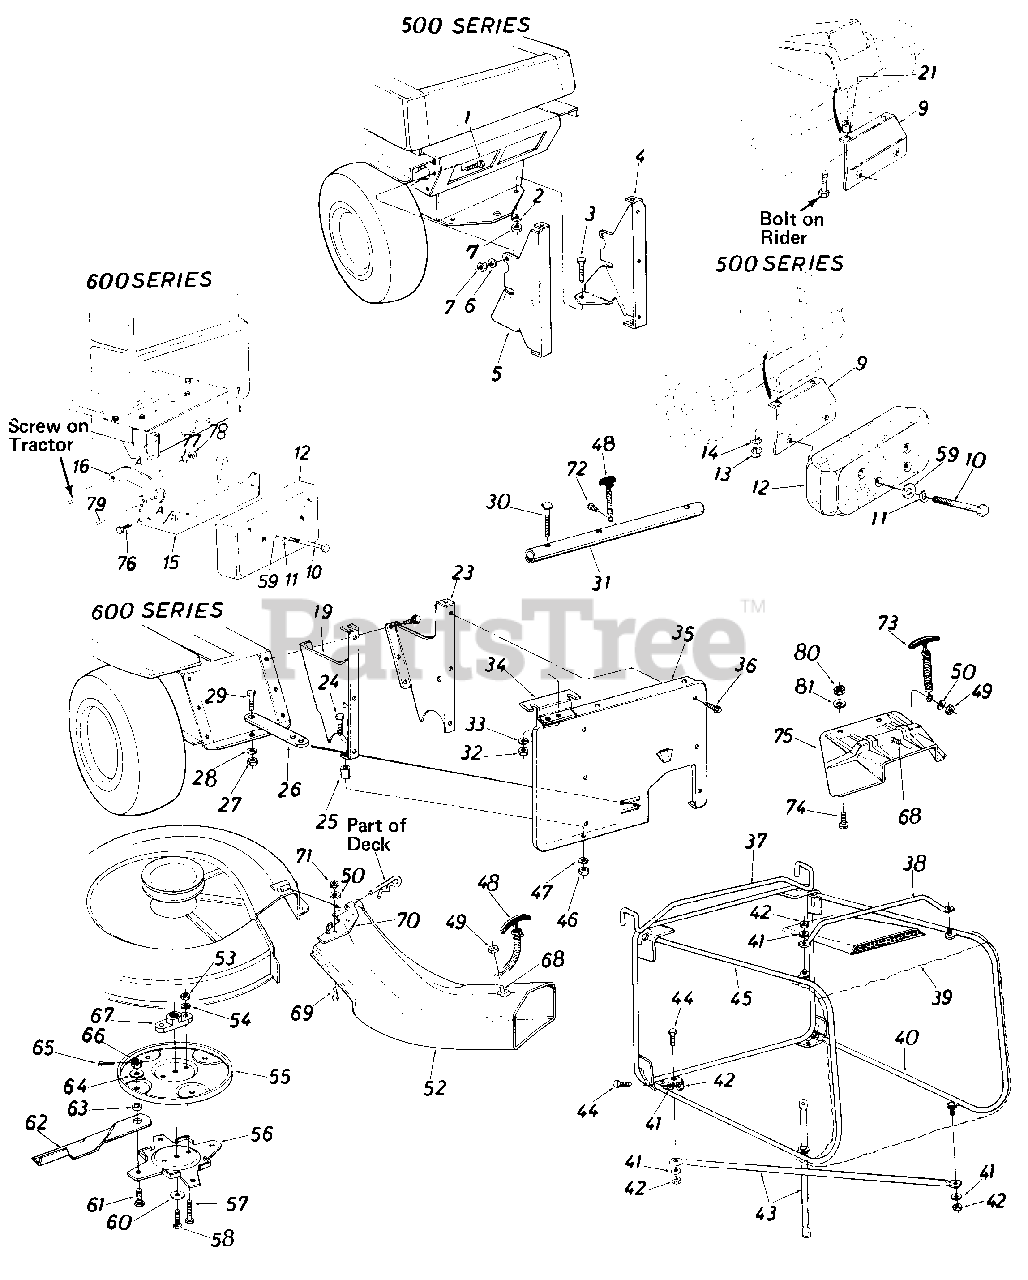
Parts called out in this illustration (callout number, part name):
1	Hex Bolt 5/16-18 x 1.0" Lg.*
2	L.-Wash. 5/16" I.D.*
3	Hex Bolt 5/16-18 x 1.0" Lg.*
4	Catcher Support Brkt-R.H.
5	Catcher Support Brkt-L.H.
6	L.-Wash. 5/16" I.D.*
7	Hex Nut 5/16-18 Thd.*
9	Counterweight Support Brkt. Ass'y .
10	Hex Bolt 3/8-16 x 4.5" Lg.
11	Belleville Wash 40" I.D. x .88" o r)
12	Counterweight 38 lbs.
13	Hex Nut 5/16-18 Thd.*
14	L.-Wash. 5/16" I.D.*
15	Counterweight Support Brkt. Ass'y.
16	Tie Strap
19	Catcher Support Brkt.-L.H.
21	Spacer .380" I.D. x 1.0" O.D. x .32" Lg.
23	Catcher Support Brkt.-R.H.
24	Hex Bolt 5/16-18 x 1.50" Lg.
25	Spacer .380" I.D. x .47" O.D. x 1.0" Lg.
28	L.-Wash. 1/2" I.D.
29	Hex Bolt 1/2-20 x 1.0" Lg.
30	Curved Carriage Bolt 5/16-18 x 1.75" Lg.
33	L.-Wash. 5/16" I.D.
34	Grass Catcher Support Plate
35	Rear Discharge Panel
36	Hex Wash. Hd. Self Tap. Scr. 1/4-20 x .50" Lg.
37	Grass Catcher Frame Ass'y.
42	Hex L.-Nut 1/2-20 Thd
43	Bottom Cross Brace
44	Hex Bolt 1/4-20 x .62" Lg.
47	L-Wash. 5/16" I.D.
48	Hook Latch Ass'y.
49	Hex L.-Nut 1/4-20 Thd.
50	Fl.-Wash. 1/4" I.D.
52	R.D. Banana Chute Ass'y.
53	Hex Nut 5/16-24 Thd.
54	L.-Wash. 5/16" I.D.
55	Upper Blade Disc
58	Hex Bolt 3/8-24 x 1.0" Lg.
59	Fl.-Wash. .39" I.D. x 1.12" 0. D.
60	Bell.-Wash. 39" I.D. x 1.38"
61	Shld. Bolt. .50" Dia. x .360 Spec.
62	30" Blade Tip
63	Spacer .505" I.D. x .75" O.D. x 1.25" Lg.
64	Fl.-Wash. .50" I.D. x 1.25" O.D.
65	Cotter Pin 3/32" Dia. x 1.0" Lg.
66	Hex Slotted Nut 1/2-20 Thd.
67	Blade Adapter
68	Hex Bolt 1/4-20 x .50" Lg.
69	Truss Mach. Scr. 1/4-20 x .50" Lg.
72	Hex AB Tap Scr. 1/4 x .62" Lg.
73	Hook Latch Ass'y. 7" Lg.
74	Truss Mach. Scr. 1/4-20 x 50" Lg.
75	R D Chute Extension
76	Hex Bolt 7/16-20 x 1.0" Lg.*
77	L.-Wash. 7/16" I.D.*
78	Hex Nut 7/16-20 Thd.*
79	Self-Tap. Scr. 5/16-18 x 1.0" Lg.
80	Hex L.-Nut 1/4-20 Thd.
81	Fl.-Wash. .281" I.D. x .50" O.D. x .063
